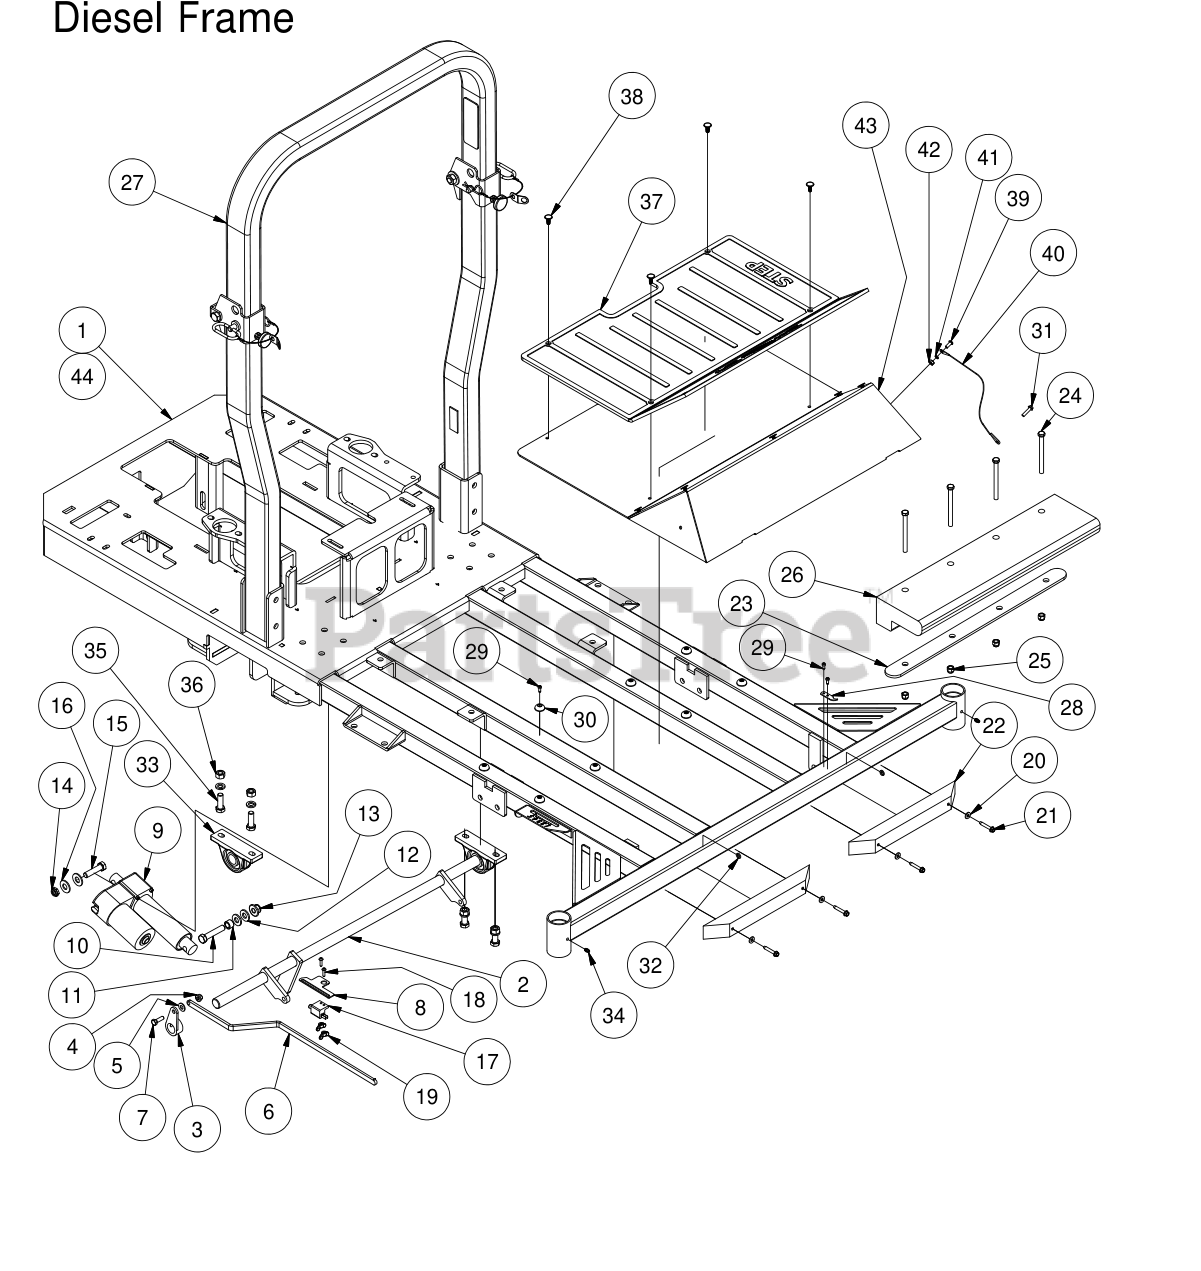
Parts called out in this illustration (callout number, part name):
1	Diesel 4cyl 72" Frame
2	Actuator Bar
3	Height Indicator Lever
4	5/16" Flange Nut
5	.360 ID Plastic Washer
6	Height Indicator Bar
7	5/16" x 1" Bolt
8	Deck Stop Bracket 2008
10	1/2" x 2 1/2" Hex Bolt
11	1/2 x 1/2 Spacer
12	.505 Nylon Spacer
13	1/2-13 Nylon Flange Nut-Orange
14	1/2" Nylock Nut (1/2 Jam)
15	1/2" x 2" Hex Bolt
16	1/2" Washer (Grade 8)
17	Deck Stop Switch
18	1024 x 1" Allenhead Bolt
19	10-24 Wing Nut
20	1/4" Flat Washer
21	1/4" x 1 1/2" Self Tapping Screw
22	14" Rubber Bumper
23	Diesel Weight Bar Bracket
24	3/8" x 4 1/2" Bolt
25	3/8 Nylock Nut
26	58lb Diesel Weight
27	2014 & Newer Diesel 2x3 Folding ROPS
28	2006 Floor Panel Stop
29	#10 x 1/2" Self Tapping Screw
30	Button Bumper
31	1/4 x 1 Hex Head tek screw
32	Brass Washer for Weld-On Hinge
33	pillow block 2bolt sealmaster
34	1/4" Press in Grease Fitting
35	1/2" x 1 1/2" Hex Bolt
36	1/2" Hex Nut
37	AOS Floor Mat
38	5/8" Christmas Tree Fastener
39	1/4" x 5/8" Buttonhead Bolt
40	Floor board Cable W/ Swivel Ends
41	1/4" Lock Washer
42	1/4" Hex Nut
43	Floor Panel
44	Diesel 4cyl 61" Frame Suspension
